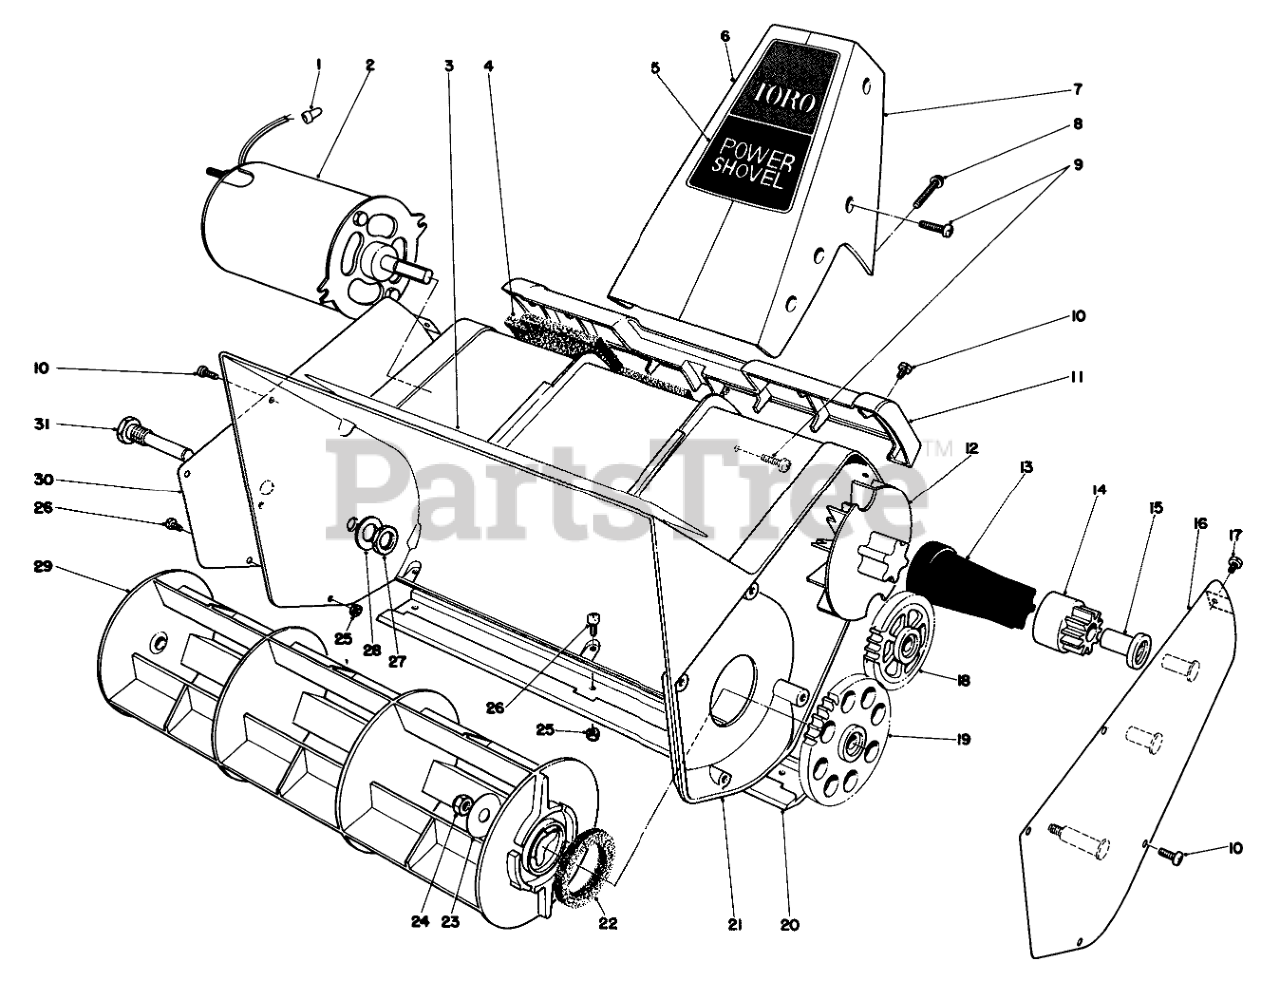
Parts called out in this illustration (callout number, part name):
1	Wire Connector
2	Electric Motor
3	Decal-U.L.
4	Foam Filter
5	HANDLE DECAL
6	RH HANDLE SUPT
7	LH HANDLE SUPT
8	SCREW-PPH
9	SCREW-PPH
10	SCREW-PPH
11	DEFLECTOR
13	DRIVE COUPLING
14	Pinion Assy. (Incl. Ref. #15)
15	BUSHING
16	Gear Carrier
17	Taptite Screw
18	Idler Gear
19	Rotor Gear (Incl. Ref. #15)
20	SCRAPER
21	Housing
22	FELT WASHER
23	WASHER
24	NUT-LOCK, NI
25	NUT-LOCK
26	SCREW-PPH
27	NUT-HEX
28	WASHER-FLAT
29	ROTOR
30	RT SIDE COVER
31	ROTOR PIN
